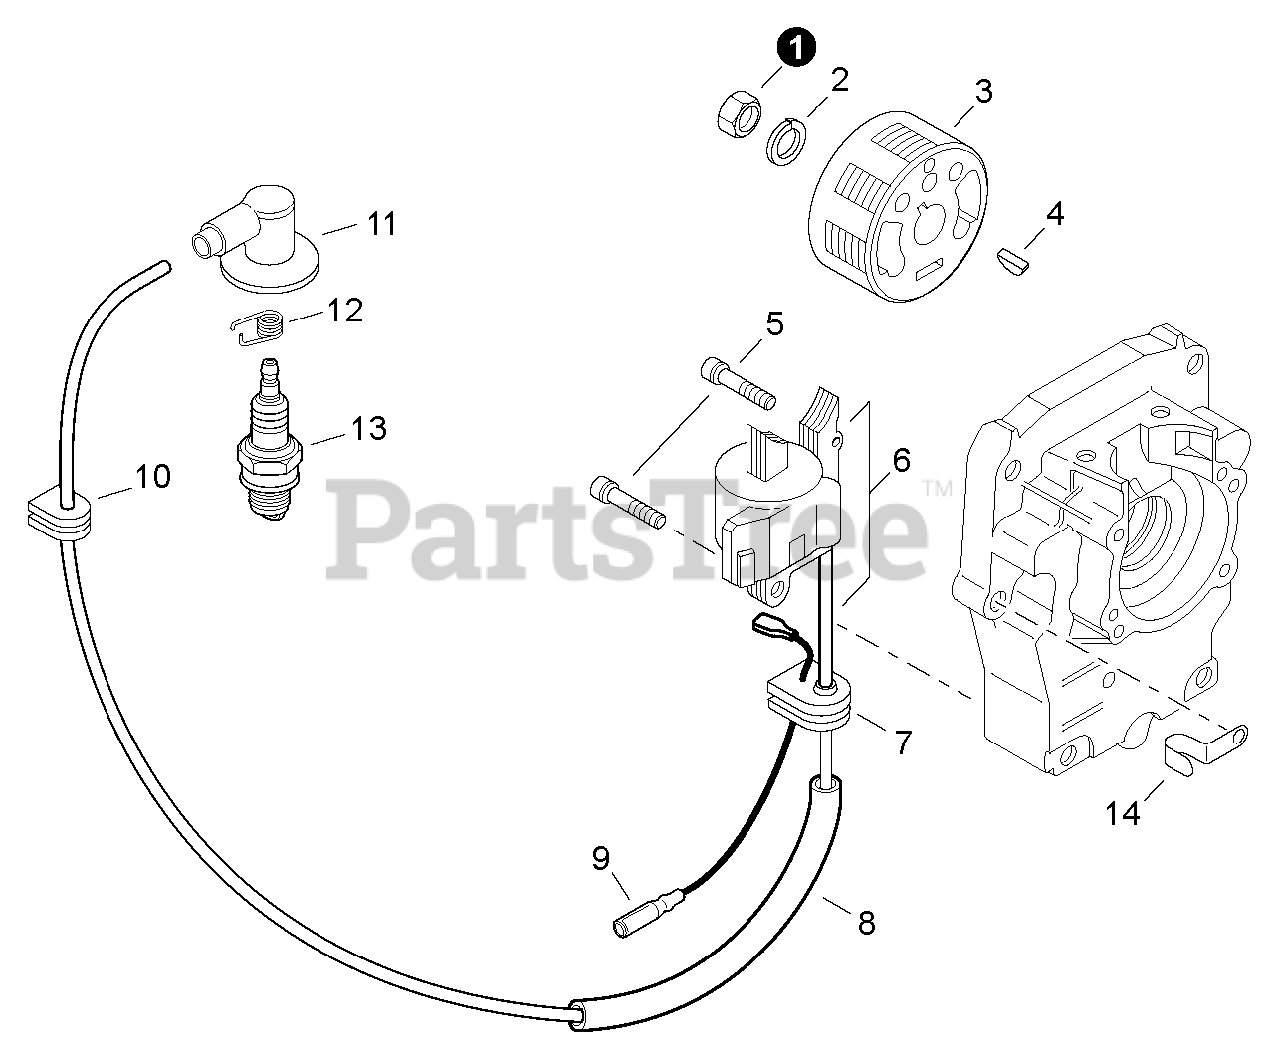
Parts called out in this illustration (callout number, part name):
1	NUT 10×1.25
2	WASHER, SPRING 10
3	FLYWHEEL
4	KEY, WOODRUFF 3×10
5	BOLT 5
6	COIL, IGNITION
7	GROMMET
8	TUBE, INSULATOR
9	WIRE, LEAD
10	GROMMET
11	CAP, SPARK PLUG
12	TERMINAL, SPARK PLUG
13	SPARK PLUG - BMR6A
14	CLIP
